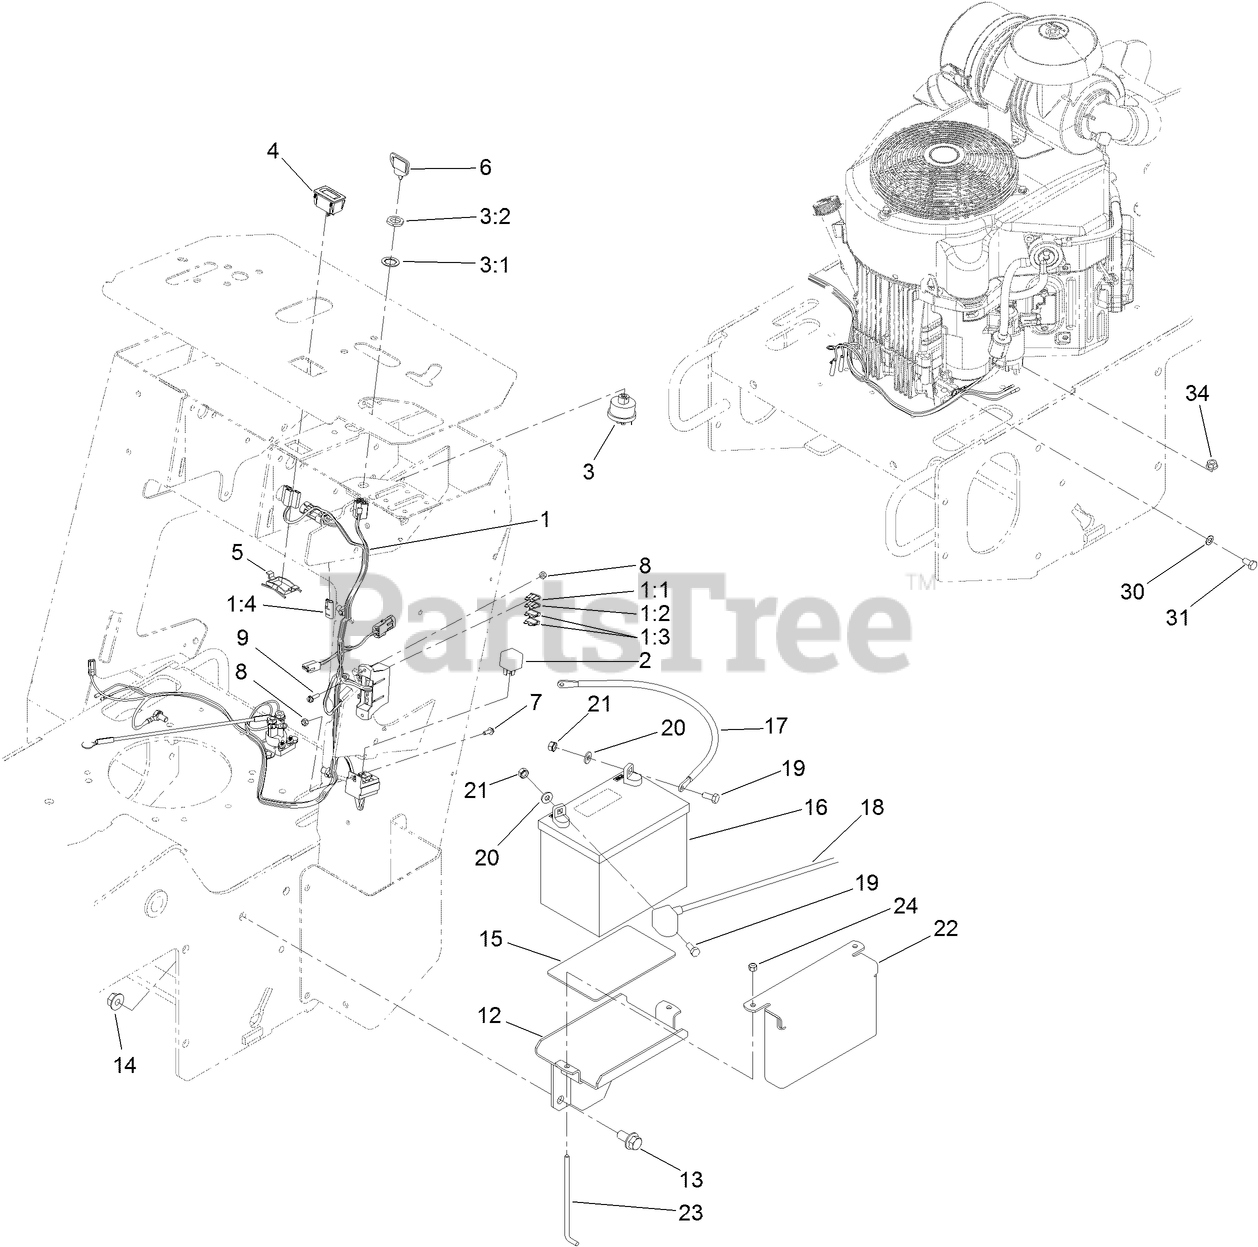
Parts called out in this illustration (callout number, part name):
1	HARNESS-WIRE
1:1	FUSE-BLADE, 30 AMP
1:2	FUSE-BLADE, 25 AMP
1:3	FUSE-BLADE, 20 AMP
1:4	CAP-PLUG
2	RELAY
3:1	WASHER-LOCK
3:2	NUT-HH
4	HOURMETER
5	CLIP-MOUNTING
6	KEY-IGNITION
8	NUT-LOCK, NI
9	SCREW-HWH
12	TRAY-BATTERY
13	SCREW-HH
14	NUT-HHF
15	PAD-SKID, ANTI
16	BATTERY-DRY
17	CABLE-BATTERY, POSITIVE
18	CABLE-BATTERY, BLACK
19	SCREW-HH
20	WASHER-FLAT
21	NUT-KEPS
22	PLATE-HOLD DOWN, BATTERY
23	HOLDOWN-BATTERY
24	NUT-LOCK, NI
30	WASHER-LOCK
31	SCREW-HH
34	NUT-HF
